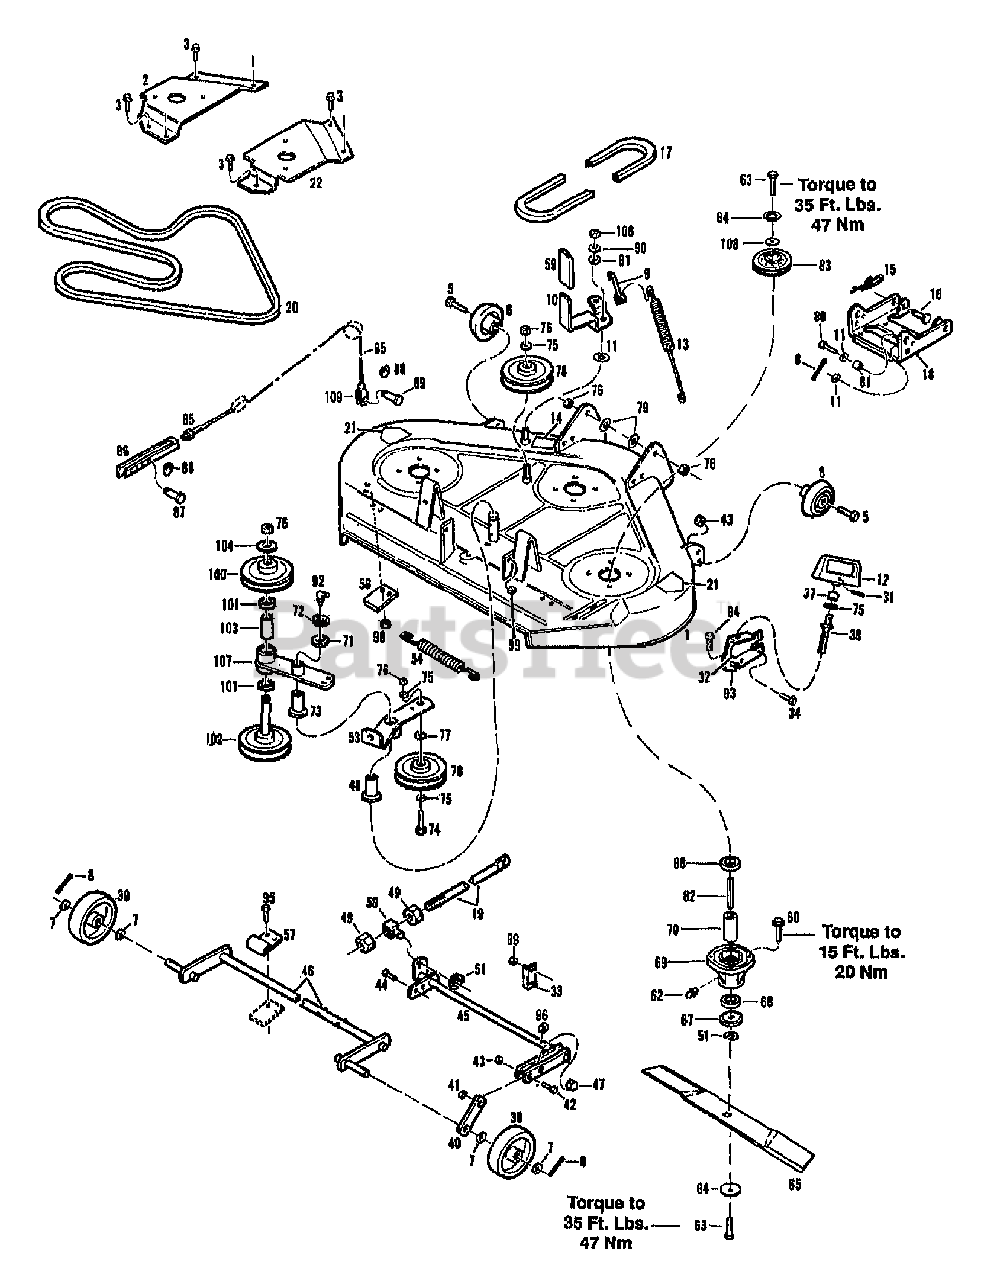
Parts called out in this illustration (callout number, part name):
1	ASSM-MOWER DECK W/DECAL
2	COVER-BELT LH
3	SCR 1/4-20X.5 FL SELF TAP
5	SCR-SHLDR 3/8-16
6	WHEEL-GAGE
7	WASHER-1.38 X.765X .06 ZP
8	PIN-COTTER .120X1.25 ZP
9	ROD-IDLER
11	WASHER-.5 DIA
12	HANDLE-HEIGHT ADJ
13	SPRING-EXTENSION
14	DECAL-BELT DRIVE
15	RING-COTTER
16	PIN-CLEVIS .62X2.50 ZP
17	BELT-V
18	ASSM-MOWER SUPPORT
19	ROD-ADJUSTER
21	DECAL-OPEI CAUTION
22	COVER-BELT RH
31	PIN-ROLL .188X1.0
32	DECAL-HEIGHT ADJUST
33	RETAINER-SHAFT
34	SCR-HH 5/16-18X.63 G5
37	SPACER-HANDLE
39	GAUGE-WHEEL
40	LINK-WHEEL SUPPORT
41	SPACER-.75X.39X.545
42	SCR-HH 3/8-16X1.5 G5 ZP
43	NUT-LOCK 3/8-16
44	SCR-HHC 5/16-18X.75 GR 5 ZP
45	ASSM-ARM HEIGHT ADJUST
46	ASSM-WHEEL SUPPORT
47	PIVOT-ADJUSTING SCR
48	BEARING-FLANGE
49	NUT-HEX
50	BLOCK-PIVOT
51	RING-RETAINING EXT .694 ID
54	SPRING-EXT
56	PLATE-DOUBLER
57	SUPPORT-SHAFT
60	SCR-HFLK 5/16-18X.75
62	FITTING-GREASE 1/4-28X2.00
63	SCR-HH 1/2-14X1.00
64	WASHER-BELLEVILLE
65	BLADE-CUTTER
65	BLADE-LIFT
67	SPACER-BLADE
68	BEARING-BALL
69	HOUSING-SPINDLE
71	SHIM-WASHER
72	RING-RET. EXT .875 ID
73	FLANGE-BEARING
74	SCR-HH 1/2-13X2.0 G5 ZP
75	WASHER-FLAT .88X.5X.06 ZP
76	NUT-TOP LOCK 1/2-13 ZP
78	PULLEY-IDLER
79	WASHER
80	SCR-HH 1/2-13X1.25 G5 ZP
81	SPACER-TUBULAR
82	SHAFT-SPINDLE
84	WASHER-LK .438 ZP
85	ASSM-CABLE(MOWER DECK)
86	YOKE
87	PIN-CLEVIS .5X1.437 ZP
88	RING-CIRCLE COTTER
89	PIN-CLEVIS .375 X .937 ZP
90	WASHER-.875X.390X.134
91	WASHER-FLAT 1.0X.516X.031
92	FITTING-GREASE 90 DEGREE
93	ASSM-WHEEL BRKT
94	SCR-HH 3/8-16X1.0 G5 ZP
95	SCR-HH 5/16-18X1.25 G5ZP
96	WASHER-PLASTIC
99	NUT-TOP/LK 5/16-18 ZP
100	ASSM-SHEAVE & HUB
101	BEARING-BALL
102	ASSM-SHEAVE & SHAFT
106	NUT-H/LK 3/8-24
107	ASSM-MOUNTING ARM
108	WASHER-1.25X.5X.083 ZP
109	CABLE END-CLEVIS
